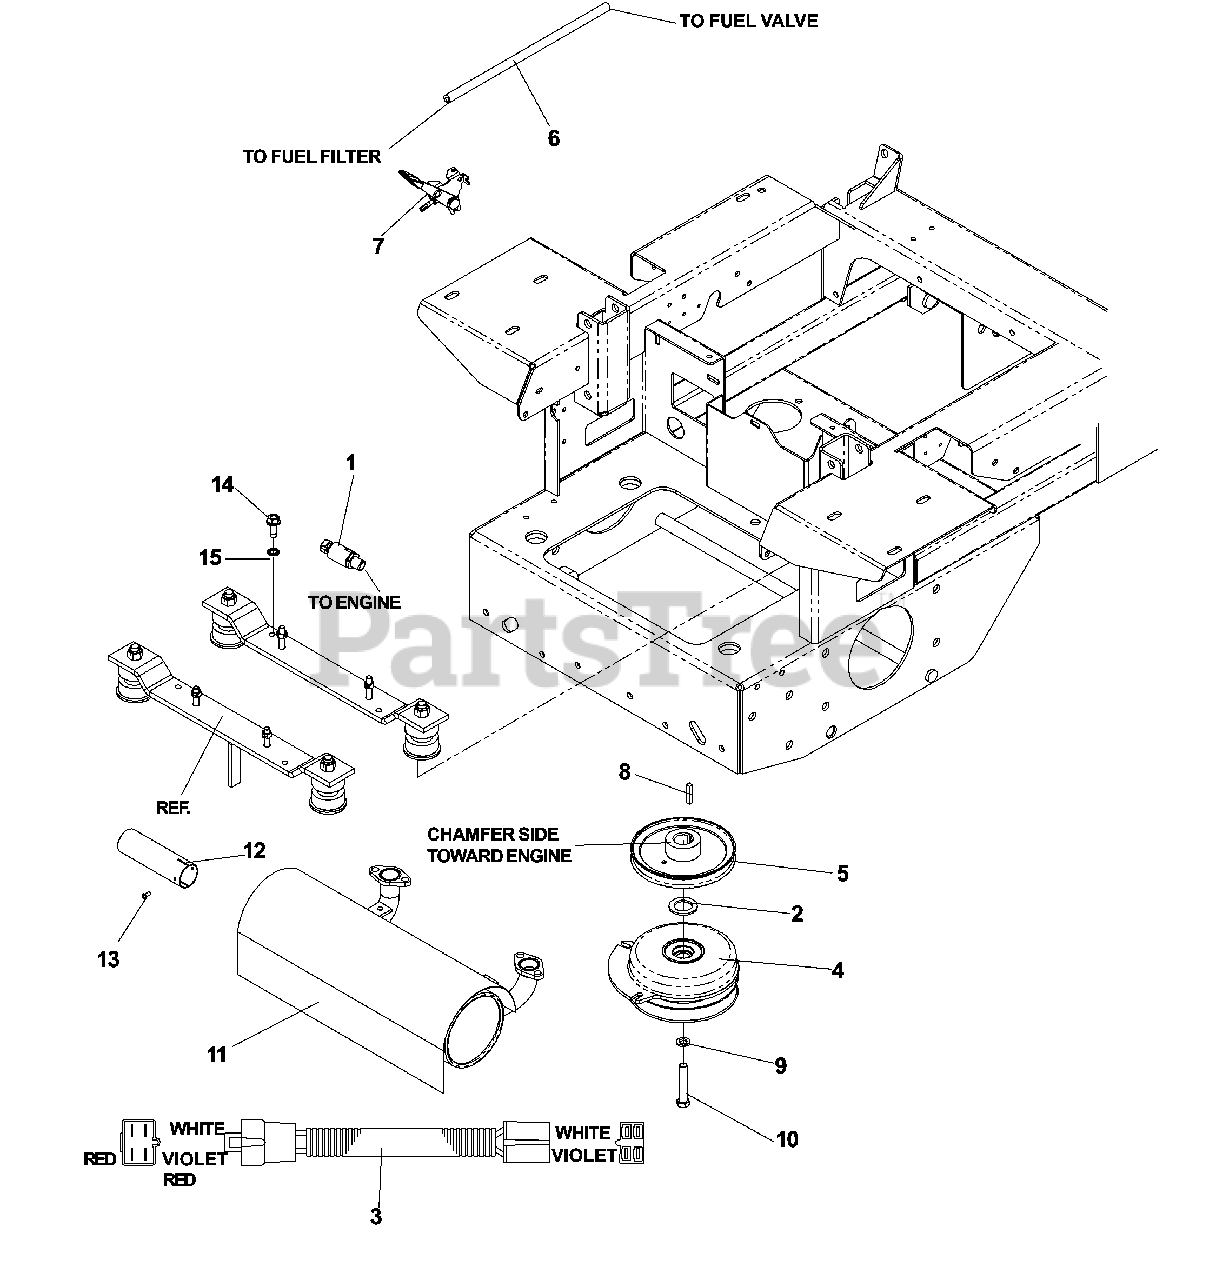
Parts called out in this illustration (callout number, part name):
1	OIL DRAIN FITTING
2	BUSHING, 10GA MACHINERY
3	KOH PIGTAIL
4	CLUTCH-200 FT LB(RPLS 5218-102
6	FUEL LINE 13"
7	CHOKE CABLE
8	KEY, 1/4 SQ X 1 1/4
9	WASHER 7/16 LOCK
10	BOLT 7/16F X 2 1/2
11	MUFFLER
12	TUBE, EXTENSION, MUFFLER
13	SCR #8 X 1/2 PHIL HD DRILL BLK
14	BOLT 3/8-16 X 1.0
15	WASHER 3/8 EXT STAR ZD
